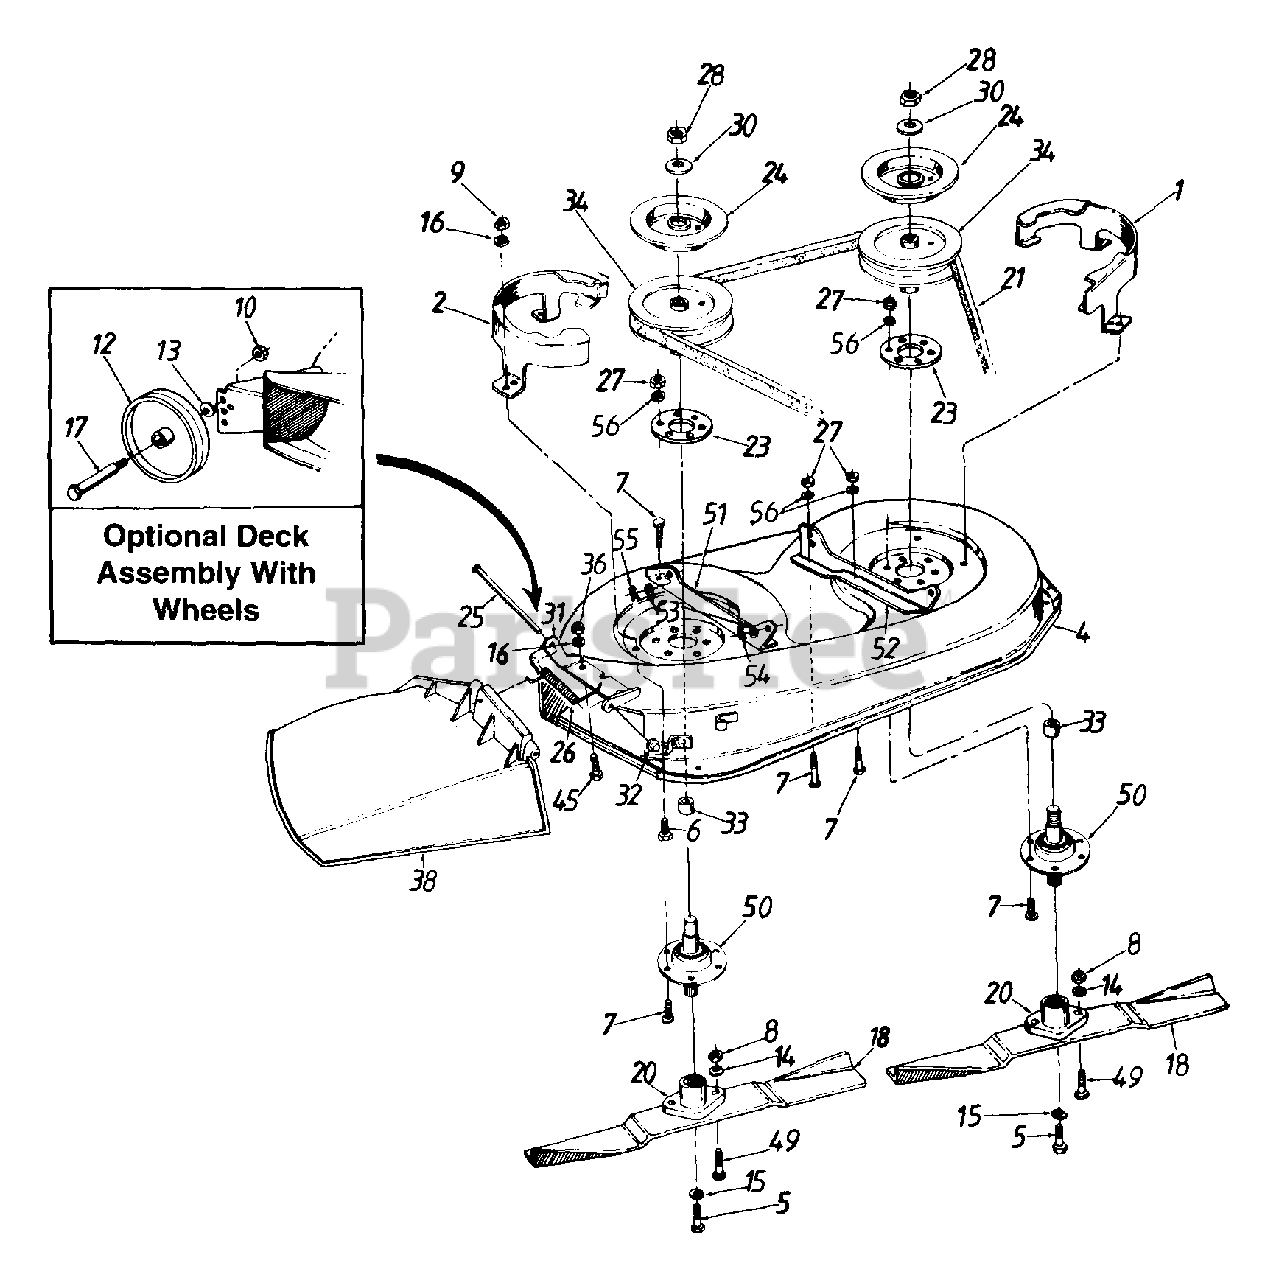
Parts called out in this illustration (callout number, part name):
5	Hex Bolt 3/8-24 x 1.0" Lg.
6	Hex Bolt 1/4-28 x,62" Lg.
7	Hex Bolt 5/16-24 x .75" Lg.
8	Hex Nut 5/16-24 Thd.
9	Hex Nut 1/4-28 Thd.
10	Hex L-Nut 3/8-16 Thd.
12	Deck Wheel
13	Bell-Wash..380" I.D. x .88"
14	L-Wash. 5/16" I.D.
15	L-Wash. 3/8" I.D. H.D.
16	Bell-Wash..265" I.D. x .75
17	Shld. Bolt .498" Dia. x 1.53"
18	High-Lift Blade
20	Blade Adapter
21	V-Belt
24	Brake Disc
25	Hinge Pin
26	Torsion Spring
27	Hex Nut 5/16-24 Thd.
28	Hex Jam Nut 5/8-18 Thd.
30	L-Wash. 5/8" I.D.
31	Hinge Mtg. Brkt.
32	Push Nut
33	Spacer
34	5" Dia. Pulley
36	Hex Nut 1/4-20 Thd.
38	Chute Ass'y. Comp.
45	Truss-Mach. Scr. 1/4-20 x .62" Lg.
49	Hex Bolt 5/16-24 x 1.0" Lg.
50	Blade Spindle Complete
51	Deck Bracket - R.H.
52	Deck Bracket - L.H.
54	Hairpin Clip 3/8" Dia.
55	Cotter Pin .75" Lg.
56	Bell-Wash..34" I.D. x .88" O.D.
